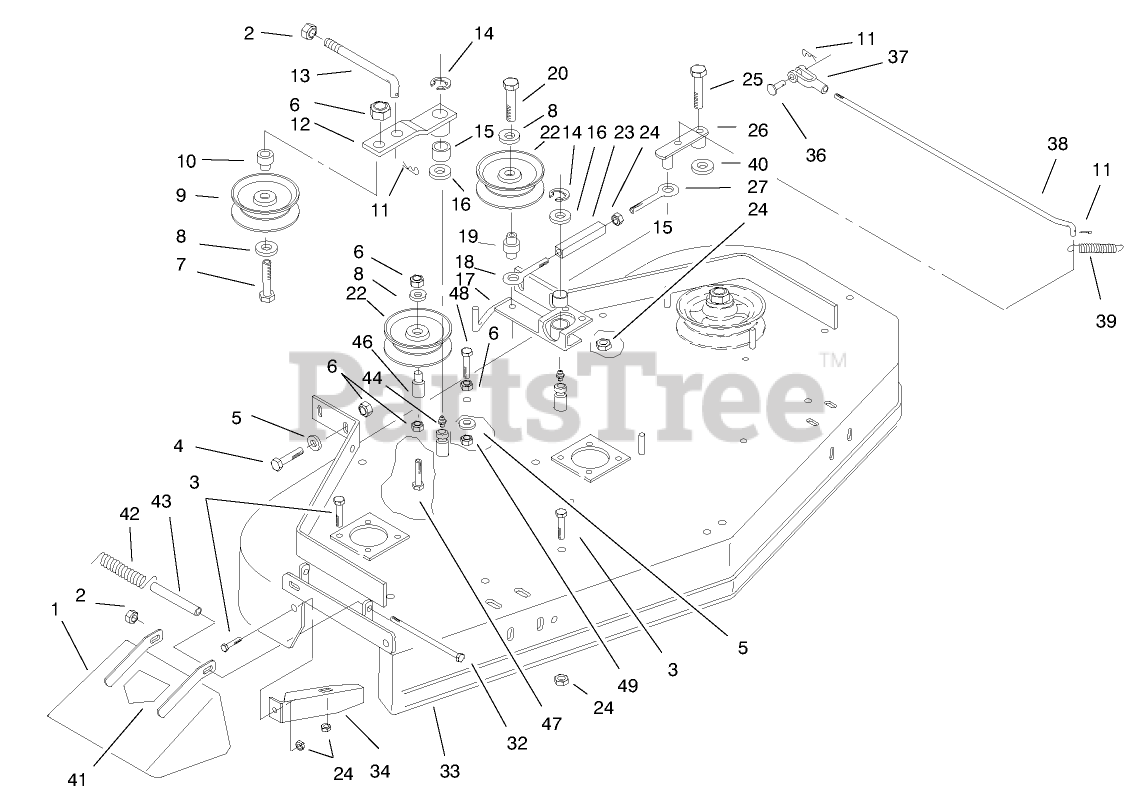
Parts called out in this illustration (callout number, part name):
1	Chute-Discharge
2	NUT-LOCK, NI
3	Screw-HH
4	SCREW-HH
5	Washer
6	NUT-FLANGE
7	SCREW-HH
8	WASHER-FLAT
9	Pulley-Idler
10	Bushing
11	PIN-COTTER
12	Idler Arm Assembly
13	Rod-Tension
14	Ring-Snap
15	Bearing
16	Spindle Washer
17	Engagement Arm w/Bushing
18	Eye Bolt
19	Bushing
20	Bolt-Whizlock
22	Pulley-Idler
23	Turnbuckle Body
24	NUT-HF
25	Bolt-Shoulder
26	Assist Arm ASM
27	Eye Bolt
32	Screw-HH
33	Deck ASM w/ Decals
34	Baffle Weldment
36	Pin-Clevis
37	Yoke
38	Linkage-Assist Arm
39	Spring-Extension
40	WASHER-THRUST
41	DECAL-DANGER
42	Spring-Deflector
43	Spacer-Spring
44	FITTING-STRAIGHT
46	Bushing
47	TAP Bolt
48	SCREW-HH
49	NUT-HEX
